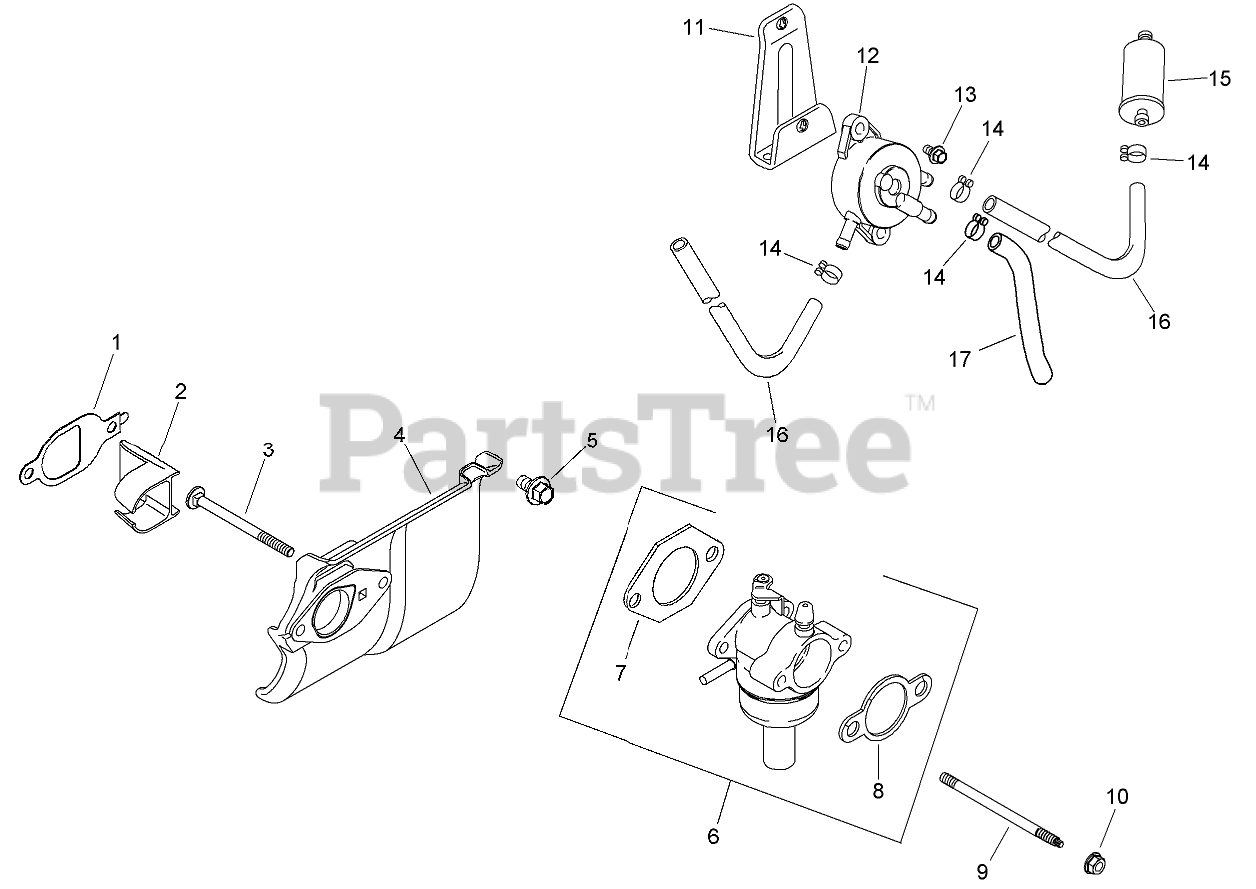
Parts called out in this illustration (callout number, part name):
1	GASKET-DEFLECTOR, HEAT
2	INSERT-PORT, INTAKE
3	STUD-CARBURETOR
4	DEFLECTOR-HEAT
5	Screw-Flange, Hex (M6x1.0x20)
6	Carburetor ASM (Includes Gaskets)
7	Gasket-Carburetor
8	Gasket-Base, Air Cleaner
9	Stud-Mounting, Carburetor (M6X1.0X100)
10	NUT-FLANGE (M6X1.0)
11	BRACKET-MOUNTING, FUEL PUMP
12	PUMP-FUEL
13	SCREW-HHFTF (M5X.80X10)
14	CLAMP-HOSE, SPRING (1/2)
15	FILTER-FUEL
16	LINE-FUEL (24.0 CUT TO LENGTH)
17	Line-Fuel (10 Inch)
